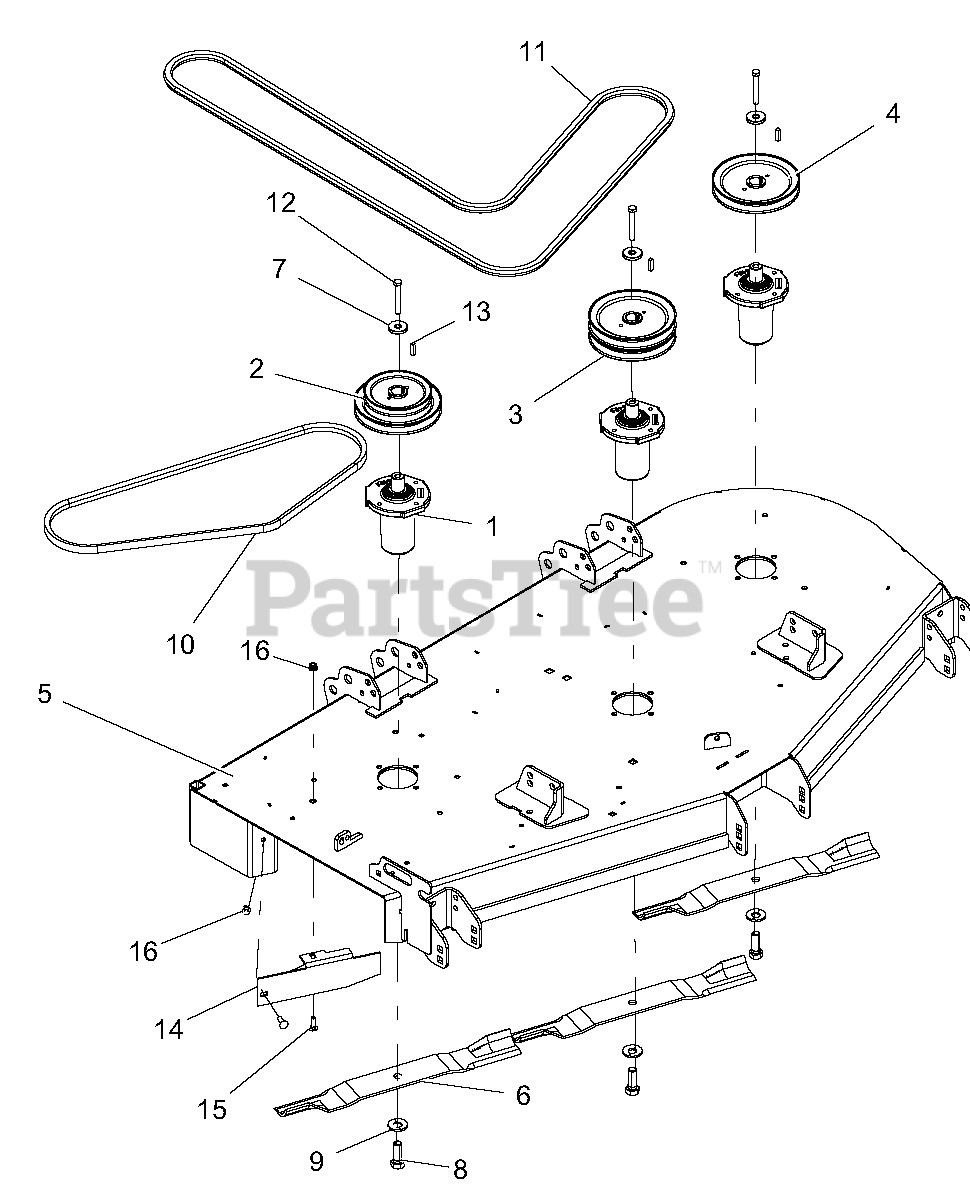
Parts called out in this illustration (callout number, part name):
1	ASM, SPINDLE - DUCTILE
2	PULLEY, DBL-1"IDX6.75"&4.25"OD (SN 000101 - 020999)
3	PULLEY, DOUBLE 1"ID X 6.75"OD-BLACK
4	PULLEY, V-1" ID X 6.75" OD-BLACK
5	WLDMT, 60" SIDE DISCH DECK-RED
6	BLADE, 20.5"
7	RETAINER, SHEAVE SPINDLE
8	BLT, HEX .62-18X1.75 GR8 YWZC
9	WSHR, BLVL .63X1.625X.14
10	BELT, B 63.00 RAW COGGED
11	BELT, BB 118.00 WRAPPED HEX
12	BLT-HEX .38-16X2.75 GR8 YWZC
13	KEY-SQ .250X.250X1.00 RC 40-50
14	BAFFLE, DISCHARGE, 60"
15	@BLT-RDHDSQSHNK .31-18X1.00 G5 Y
16	NUT-LK-NYL-FLG .31-18 YWZC
